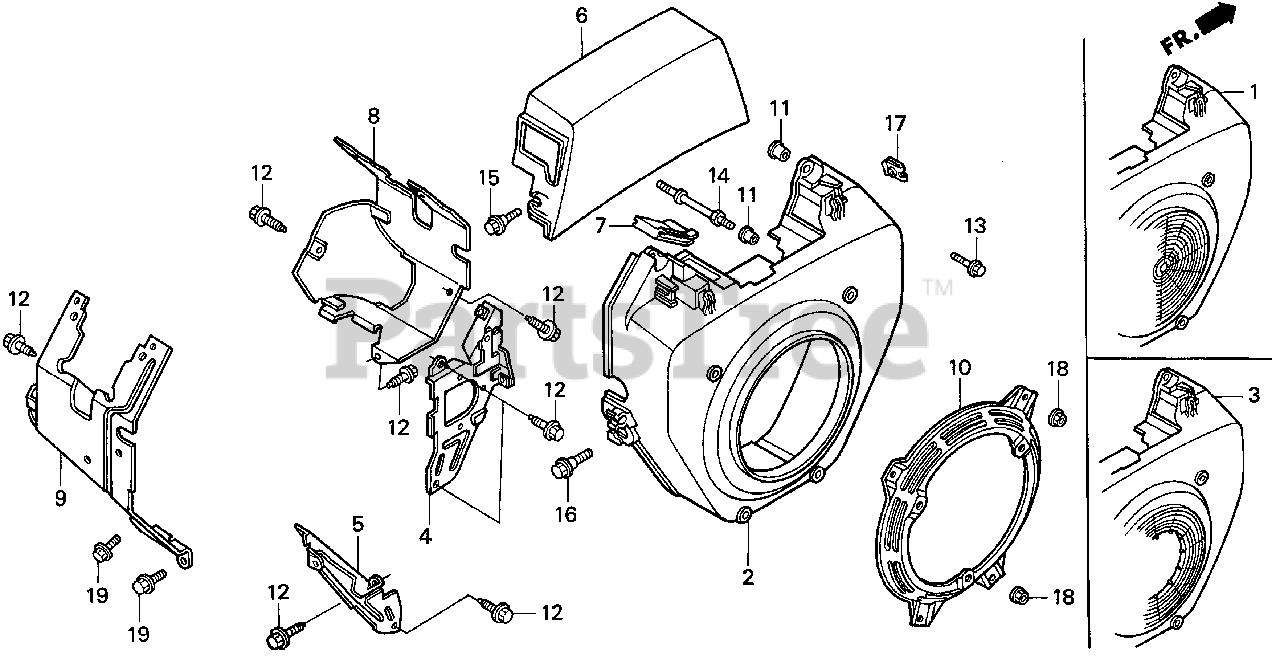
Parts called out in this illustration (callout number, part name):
1	COVER, FAN *R8* (BRIGHT RED)
4	PLATE, R. SIDE
5	PLATE, L. SIDE
6	HOOD, FAN COVER
8	SHROUD, R.
9	SHROUD, L.
11	COLLAR B, TAILLIGHT
12	BOLT, FLANGE (6X12) (CT200)
13	BOLT, FLANGE (6X23)
14	BOLT, STUD (6X75)
15	BOLT, FLANGE (6X20)
16	BOLT, FLANGE (6MM) (BLACK)
17	NUT, SPRING (6MM)
18	NUT, FLANGE (6MM)
19	BOLT, FLANGE (6X8)
